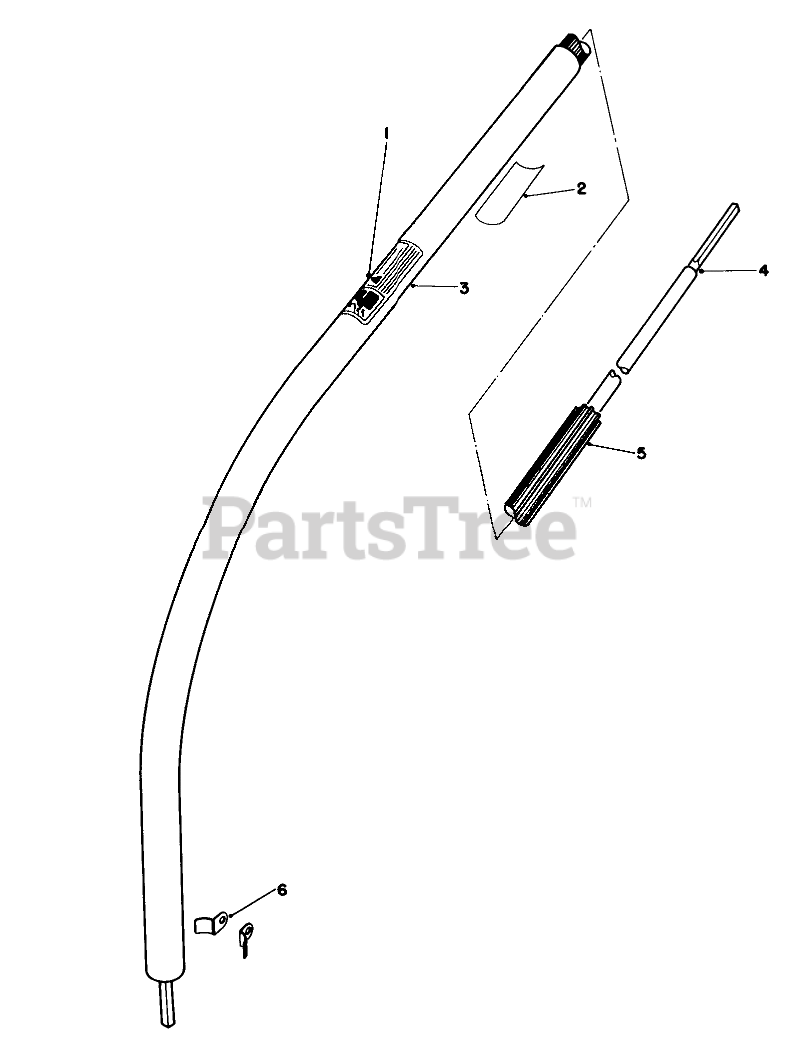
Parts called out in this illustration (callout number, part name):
1	Decal Warning
2	REP. SERIAL PLT
3	Tube-Lower Shaft Housing Assembly (Incl. Ref. #1)
4	Shaft-Flex Assembly (Incl. Ref. #5)
5	Casing-Flex Shaft
6	LOWER TUBE RETAINER
